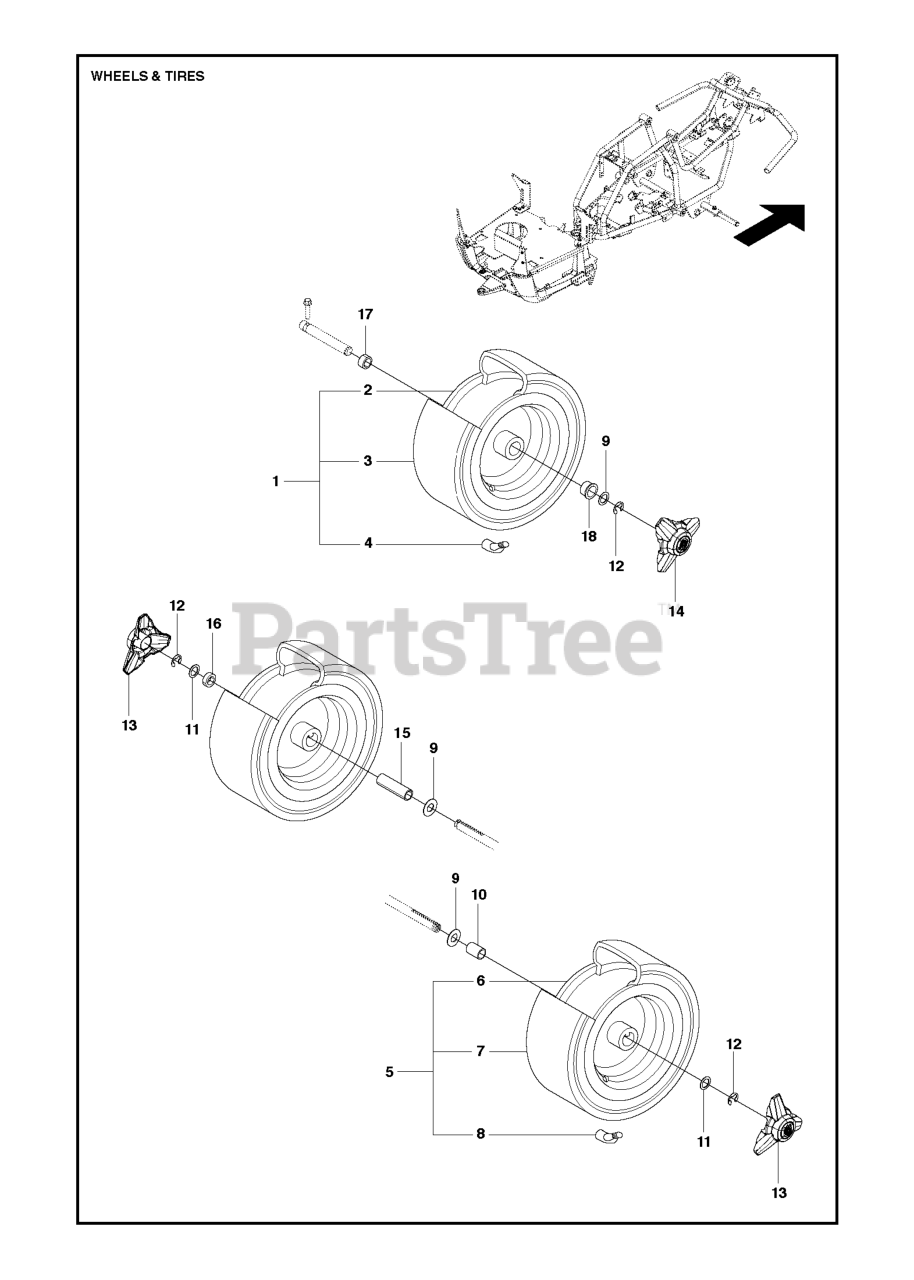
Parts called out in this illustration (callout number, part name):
4	VALVE
8	VALVE
12	RETAINING RING
17	SPACING SLEEVE
